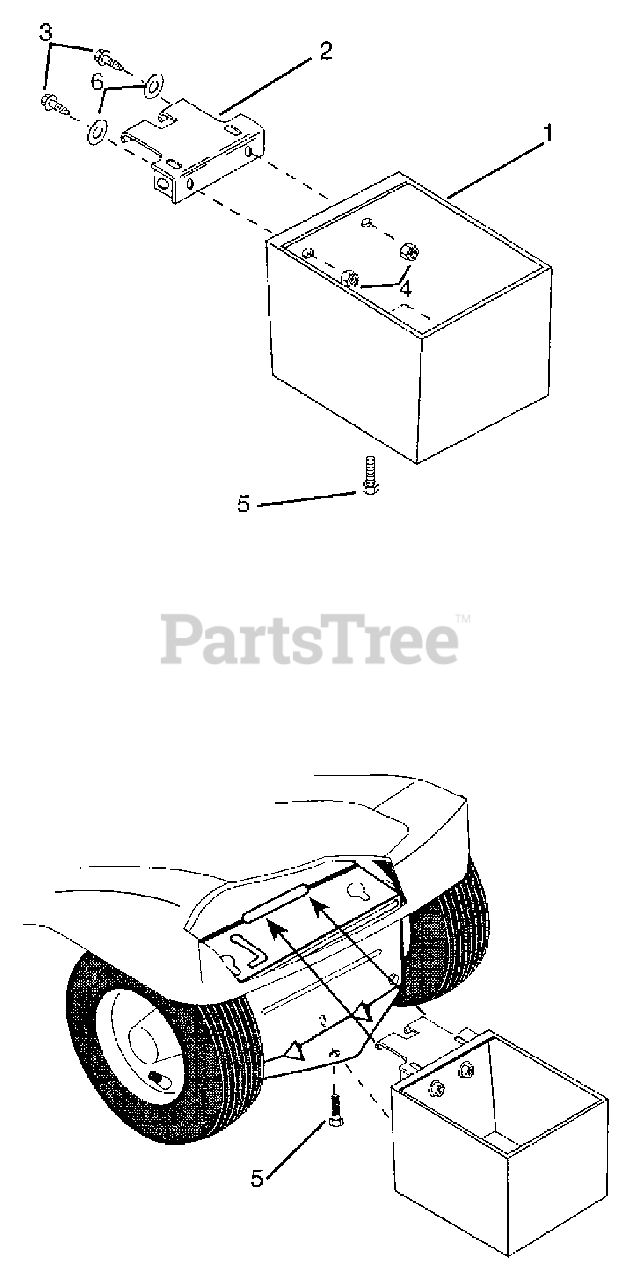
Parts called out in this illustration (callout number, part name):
1	WEIGHT BOX
2	HOOK - MOUNT
3	@BLT-HEX .31-18X.75 GR5 YWZC
4	@NUT-LK-CTR .31-18 YWZC
5	@BLT-HEX .50-13X1.00 GR5 YWZC
6	@WSHR-FL-STL.406X.812X.065 YWZ
